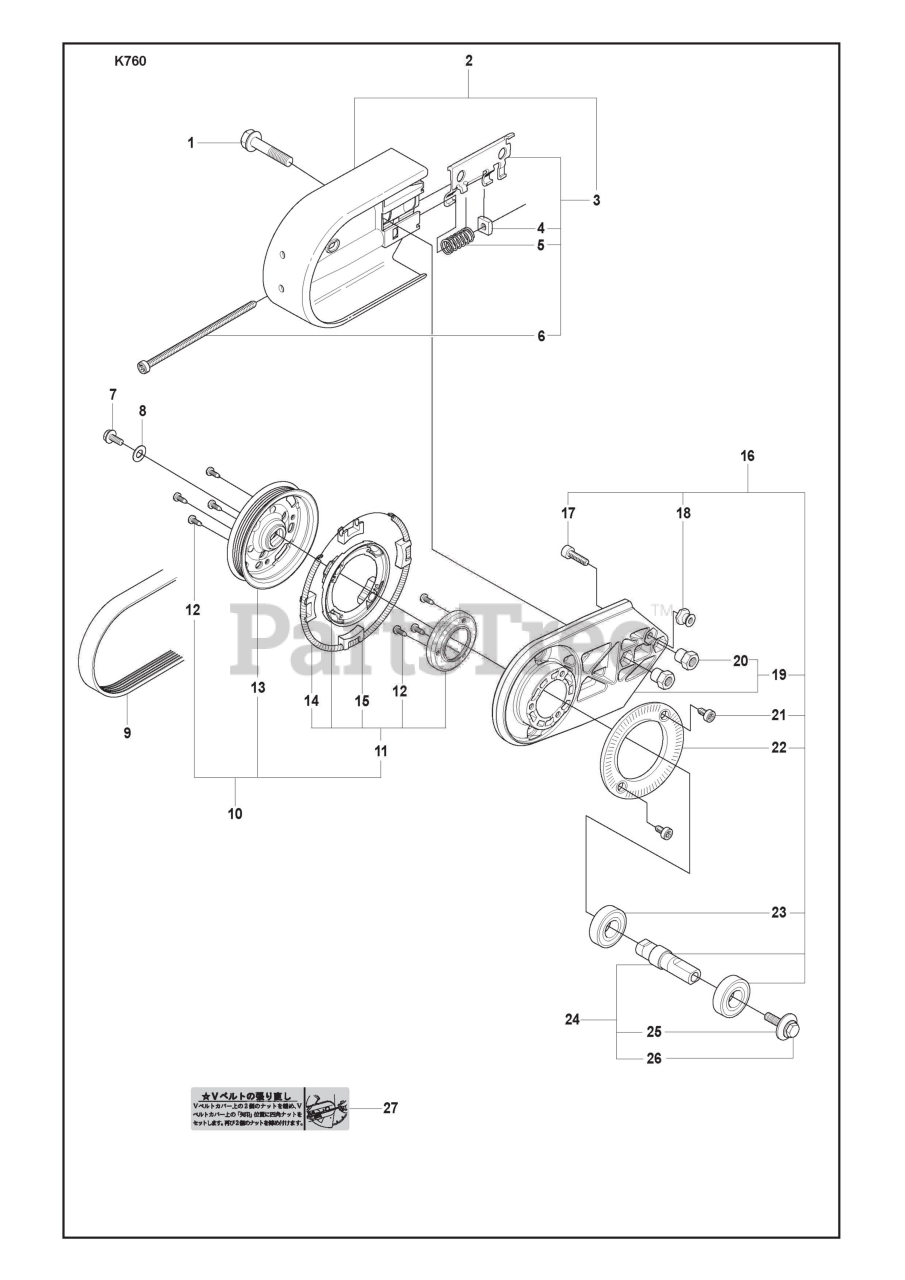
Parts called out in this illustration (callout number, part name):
1	Collar Screw
2	Belt Guard
3	Belt Tensioner Assy
5	Compression Spring
8	Washer Steel
10	Pulley With Retarder
11	Retarder Cpl
13	Pulley
15	Brake Shoe
16	Bearing Housing
18	Torsion Stop
19	Bearing Housing
22	Ratchet Flange
23	Ball Bearing
24	Shaft
25	Washer
26	Collar Screw
27	Label
